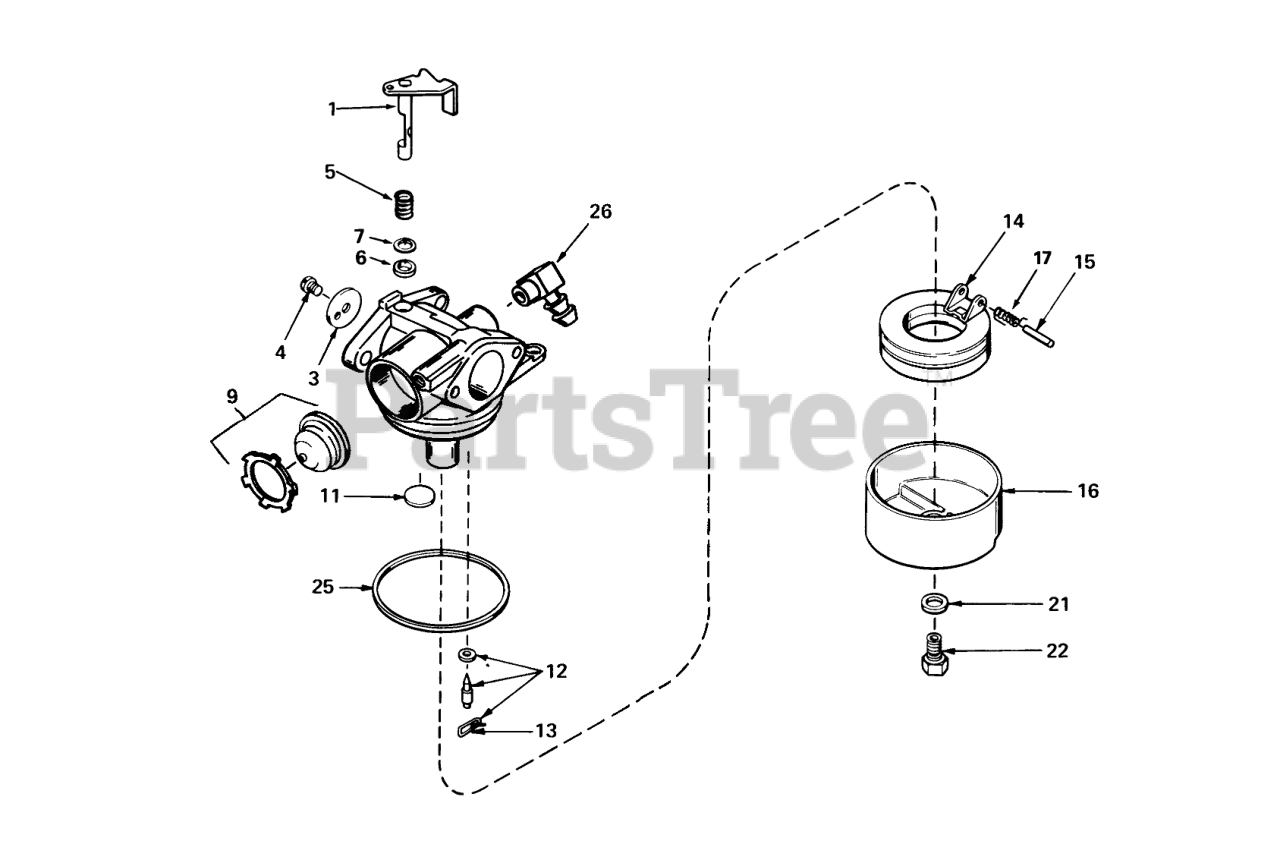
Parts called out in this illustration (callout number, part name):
1	Throttle Shaft & Lever Assy.
3	Shutter-Throttle
4	Screw-Shutter
5	Spring-Trottle, Return
6	Seal-Dust
7	Washer-Seal, Dust
9	Bulb-Primer
11	Plug-Welch, Atmospheric Vent
12	Inlet Needle, Seat & Clip Assy. (Incl. Ref. #13)
13	Clip-Spring
14	Float
15	Shaft-Float
16	Bowl-Float (no drain)
17	Spring-Float, Dampening
21	Washer-Bowl Nut
22	Nut-Float Bowl
25	O Ring-Bowl, Float
26	Fitting-Fuel
